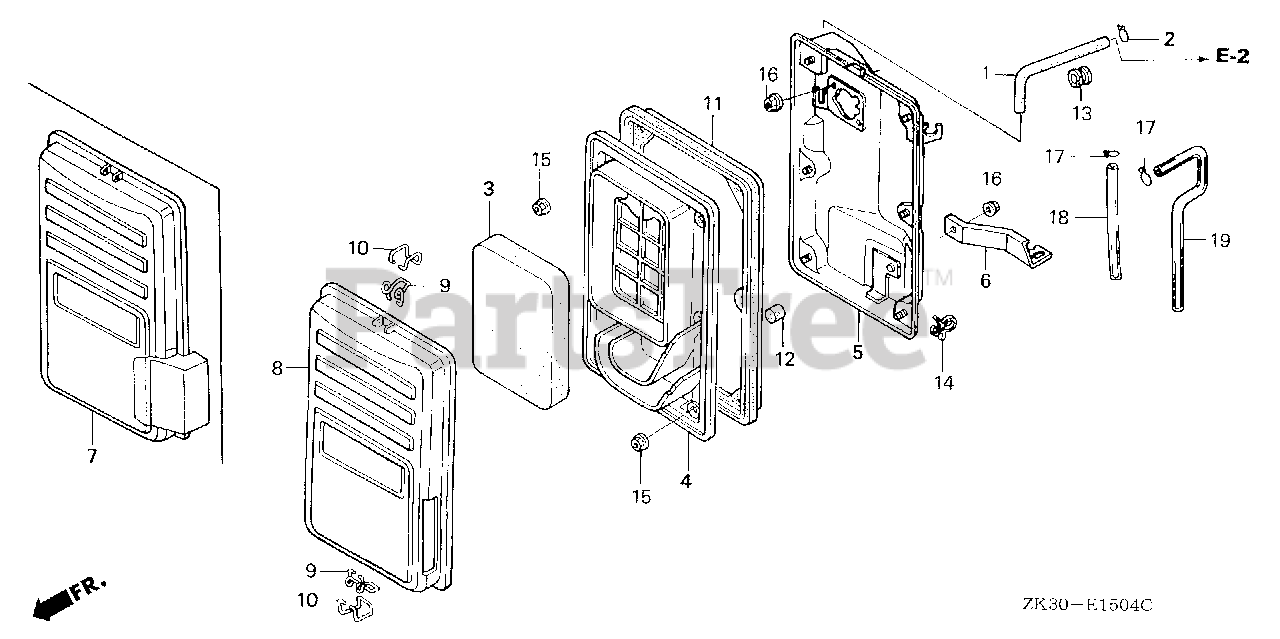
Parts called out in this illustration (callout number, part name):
1	TUBE, BREATHER
3	ELEMENT, AIR CLEANER
4	SEPARATOR, AIR CLEANER
5	HOUSING, AIR CLEANER
6	STAY, AIR CLEANER
8	COVER, AIR CLEANER
9	CLIP A, AIR CLEANER WIRE
10	CLIP B, AIR CLEANER WIRE
11	SEAL, AIR CLEANER
12	FILTER, DRAIN TUBE
15	NUT, FLANGE (5MM)
16	NUT, FLANGE (6MM)
